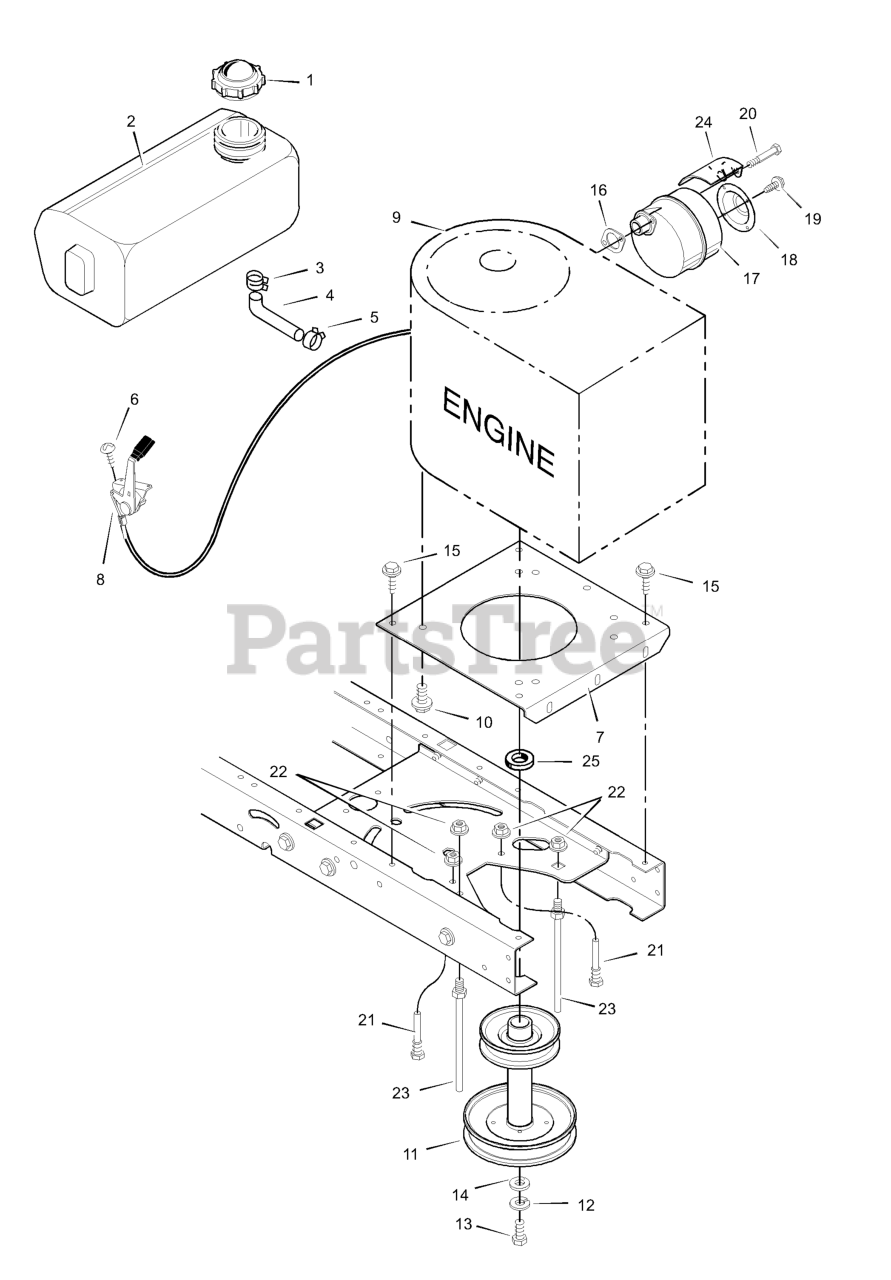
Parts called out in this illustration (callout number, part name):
1	Fuel Cap
2	Fuel Tank
3	Hose Clamp
4	FUEL LINE (must cut to length)
5	Hose Clamp
7	Plate, Engine
8	Throttle Control
9	Engine
10	BOLT, Engine Mount
11	Stack Pulley Assembly
12	LOCKWASHER
13	BOLT, Hex
17	Muffler
18	Deflector, Muffler
20	BOLT, Hex
21	GUIDE, Belt
22	NUT, Flange
23	GUIDE, Belt
24	SHIELD, Heat
